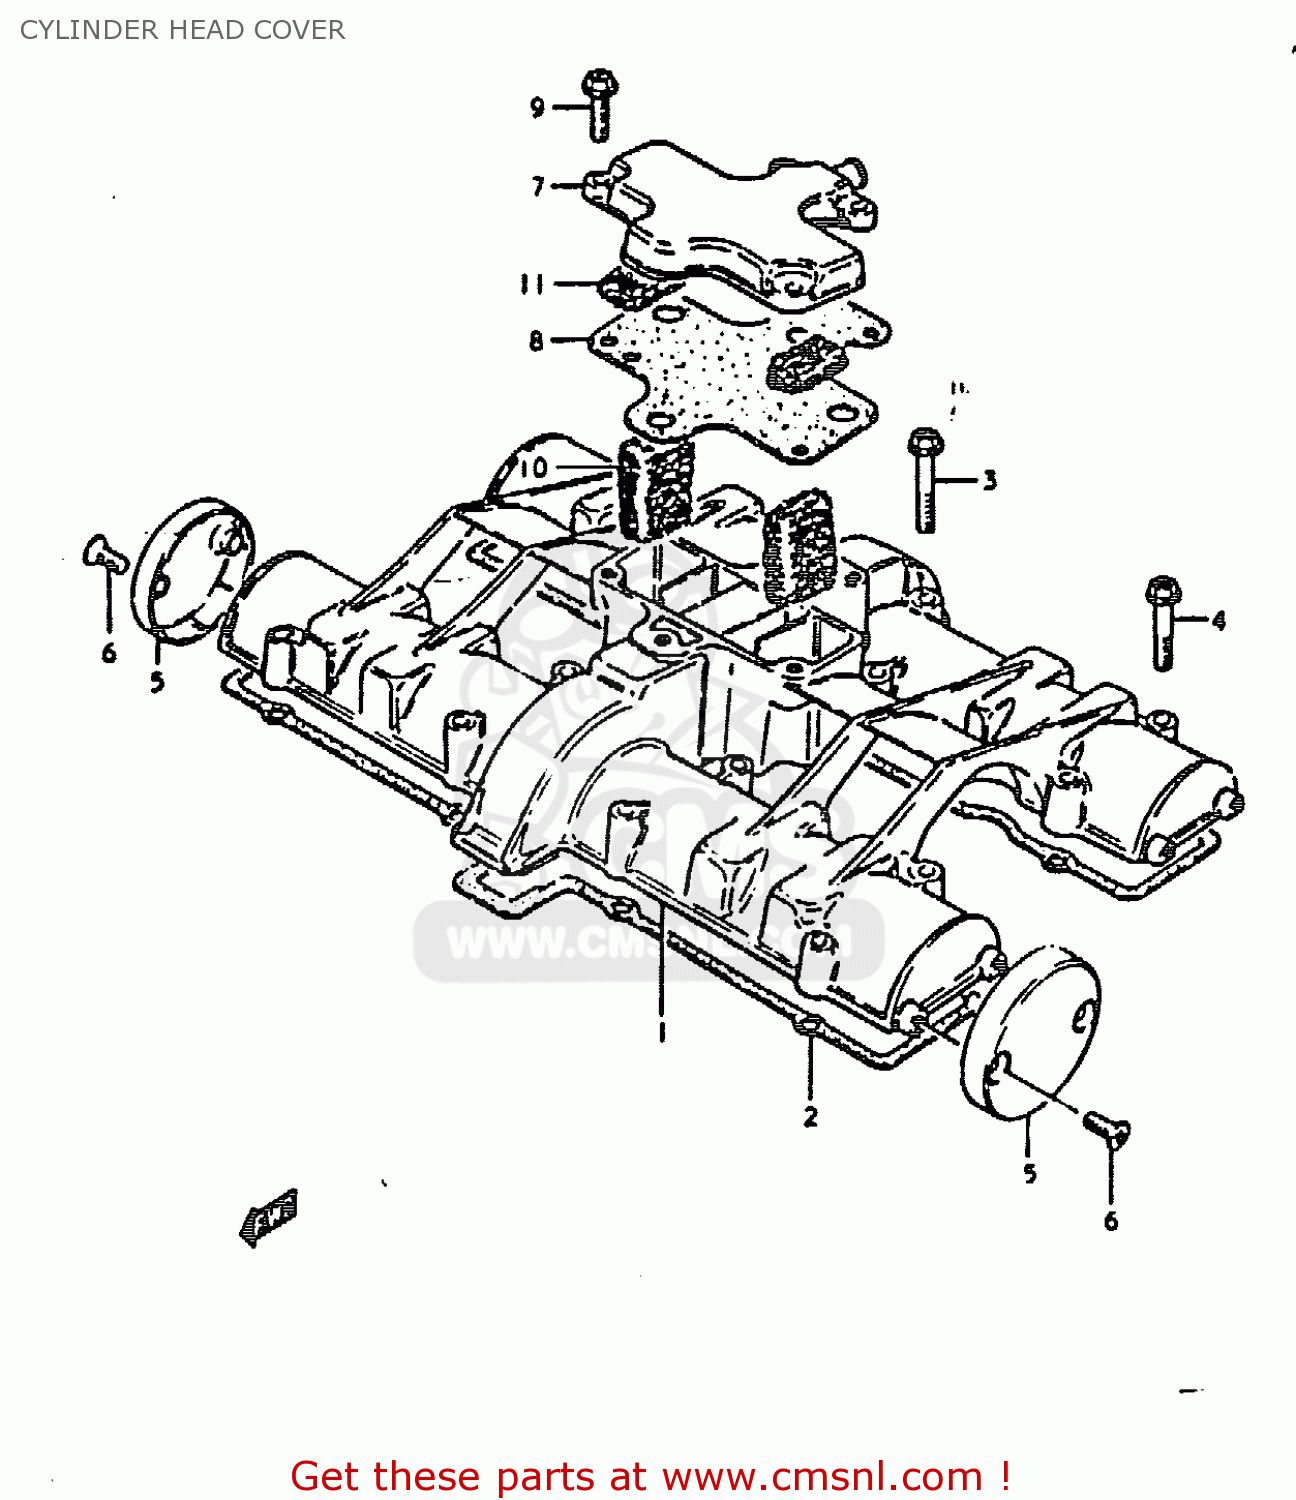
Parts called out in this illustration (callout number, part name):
1	COVER,CYLINDER HEAD
2	GASKET,CYLINDER HEAD COVER (MCA)
3	BOLT
4	BOLT 6X35
5	CAP,CYLINDER HEAD COVER
6	SCREW
7	COVER,BREATHER
8	GASKET (MCA)
9	BOLT,REAR
10	COVER,BREATHER
11	SEPARATOR,OIL BREATHER
